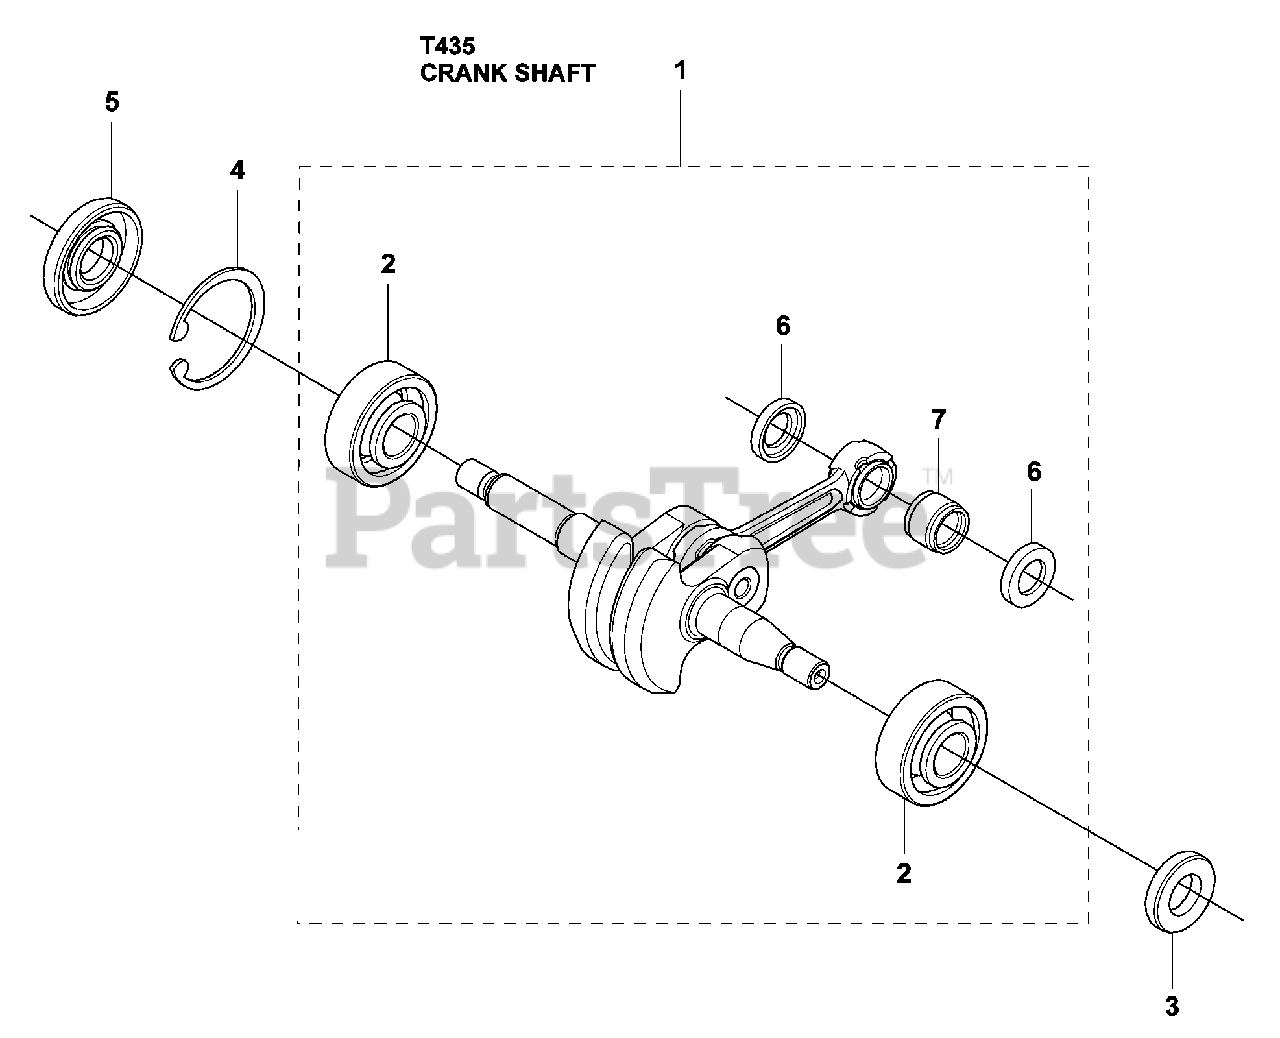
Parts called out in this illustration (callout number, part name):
1	Crankshaft comp.
2	Crankshaft bearing
3	Oil seal
4	Ring
6	Washer
7	Needle bearing
